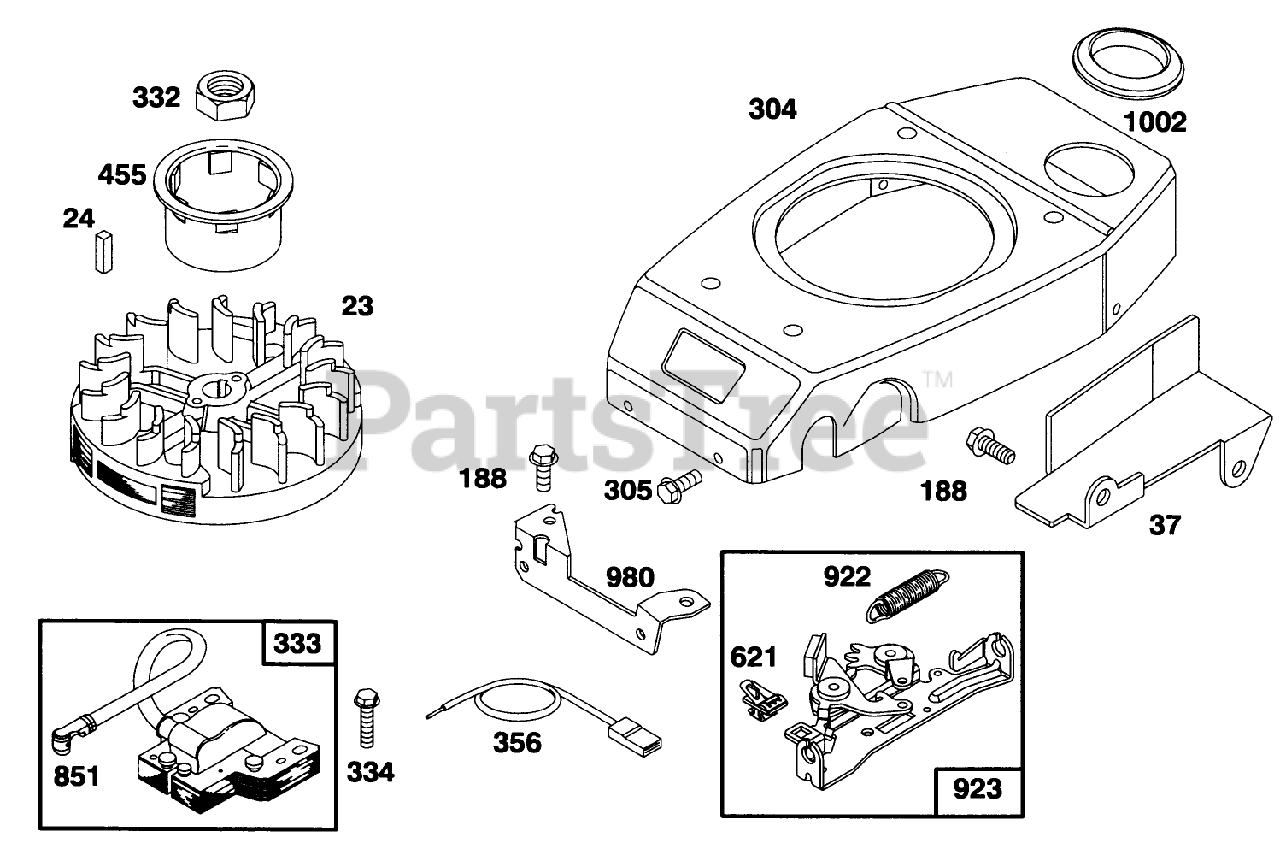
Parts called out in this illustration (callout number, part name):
24	KEY - FLYWHEEL
37	GUARD - FLYWHEEL
304	HOUSING - BLOWER
305	SCREW - HEX HEAD
332	NUT - HEXAGON
356	WIRE - GROUND
621	STOP SWITCH
980	BRACKET-BLOWER HSG
